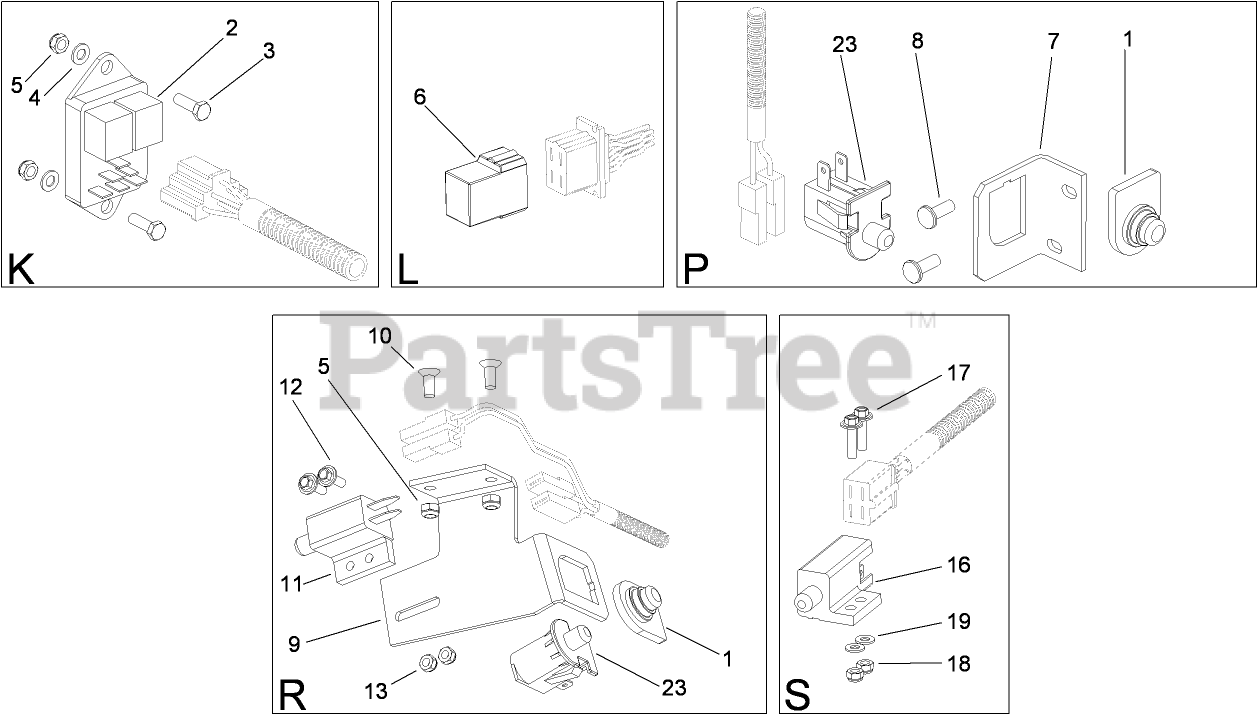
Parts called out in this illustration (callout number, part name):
1	COVER-PROTECTIVE
2	MODULE-CLUTCH
3	SCREW-HH
4	WASHER
5	NUT-LOCK
6	CIRCUIT-MEMORY
7	HOLDER-SWITCH
9	HOLDER-SWITCH
11	SWITCH-POLE, SINGLE
13	NUT-HEX
16	Switch-Delta
18	NUT-LOCK
19	WASHER
23	SWITCH-DELTA
